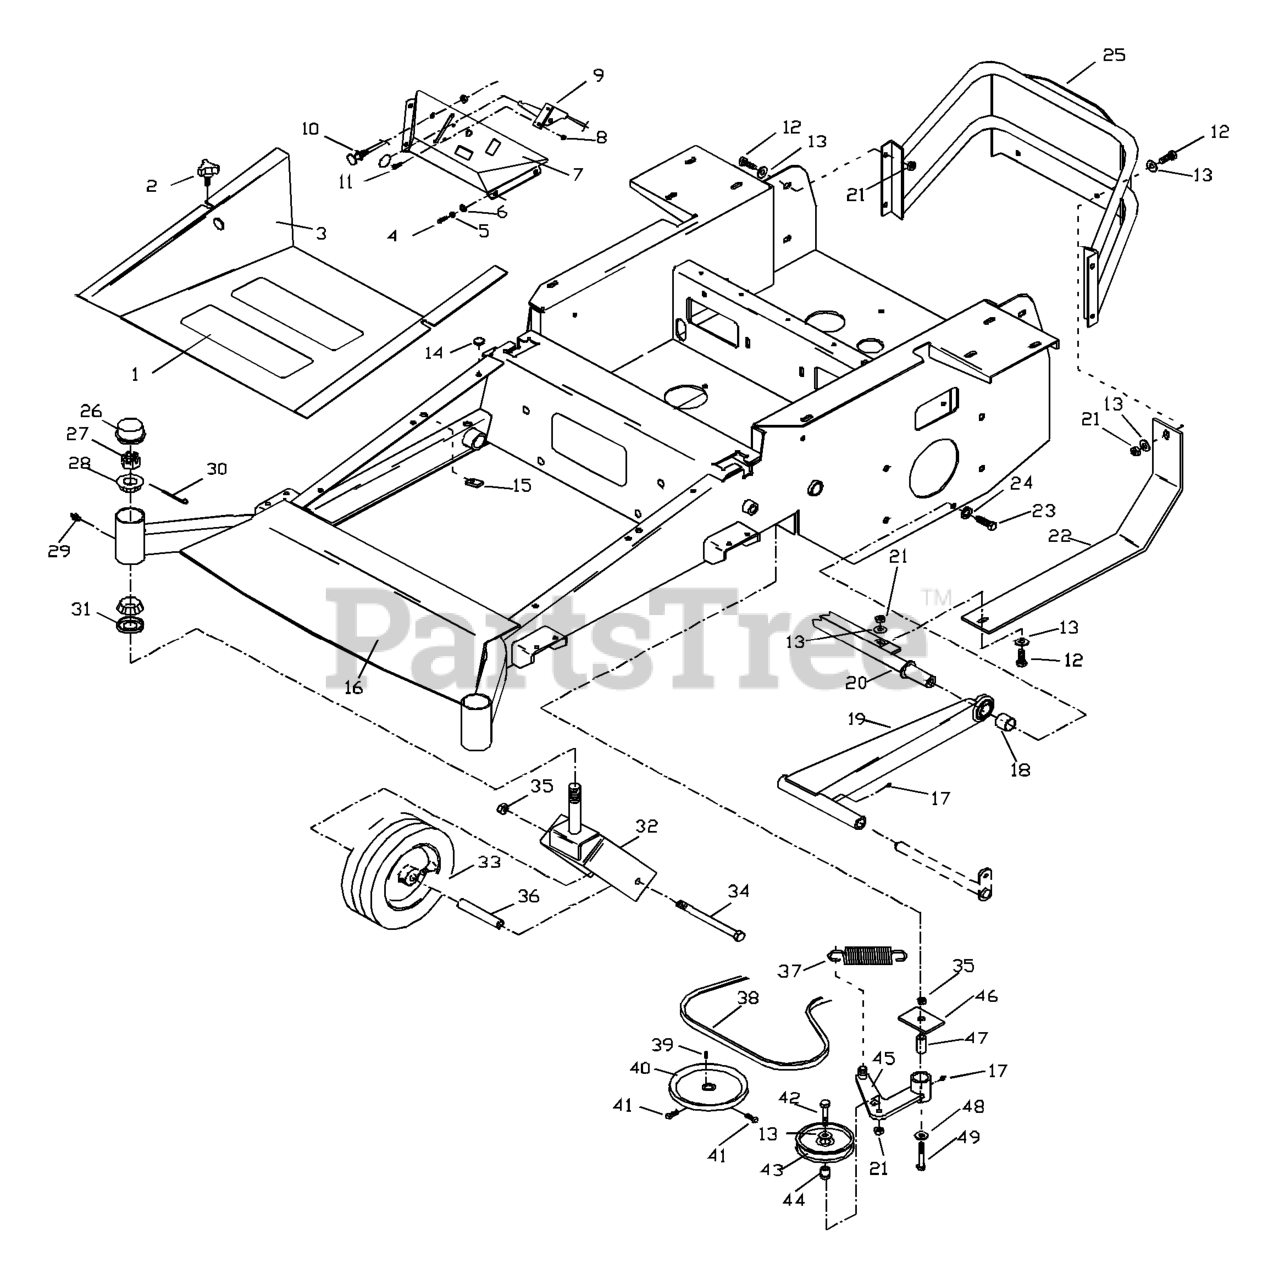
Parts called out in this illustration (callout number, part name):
1	ANTI-SKID PAD
2	KNOB W/STUD
3	FOOT PLATE WIDMT
4	HCS 1/4C X 3/4 HCS
5	LOCKWASHER 1/4"
6	WASHER 1/4 FLAT
7	CONSOLE W/DECALS
8	NUT 10-24 NYLOC
9	THROTTLE CONTROL W/BALL KNOB
10	CHOKE CONTROL, COMPLETE
11	HCS #10-24 X 1/2
12	HCS 3/8-16X1.GRD.5.ZD
13	WASHER 3/8 FLAT
14	GROMMET, BUMPER
15	U-CLIP 5/16-18 NUT RETAINER
16	MAIN FRAME W/DECALS
17	ZERK
18	SPACER, STRUT
20	CROSS SHAFT WLDMT
21	NUT 3/8C CENTERBLOCK
22	SKID PLATE
23	HCS 7/16-14 X 1 GR 5 ZD
24	WASHER 7/16 LOCK
25	REAR GUARD
26	GREASE CAP
27	NUT 1"C HEX SLOTTED
28	BEARING W/CUP
29	ZERK
30	COTTER PIN 1/8 X 2
31	BRKT-LIFT ARM
32	CASTER YOKE ORANGE
33	TIRE.ASSEM.13X5-6.SMOOTH.SILVE
33	RIM
33	TIRE - FRONT
33	ZERK 1/8 NPT
33	BEARING RETAINER
33	VALVE STEM TR-412
33	ROLLER BEARING
34	SCREW 1/2C X 7 1/2 HEX CAP
35	NUT 1/2-13 HEX NYLOC ZD
36	SPACER, CASTER
38	PUMP BELT
39	KEY 5 MM SQ X 25 MM
41	SCREW 5/16C X 5/8 SQ HEAD
42	HCS 3/8-16 X 1 3/4 GR5
43	IDLER PULLEY
44	BUSHING, IDLER FLANGE
45	IDLER ARM WLDT
47	PIVOT BUSHING
48	WASHER 1/2 FLAT
49	HCS 1/2C X 3 1/4
